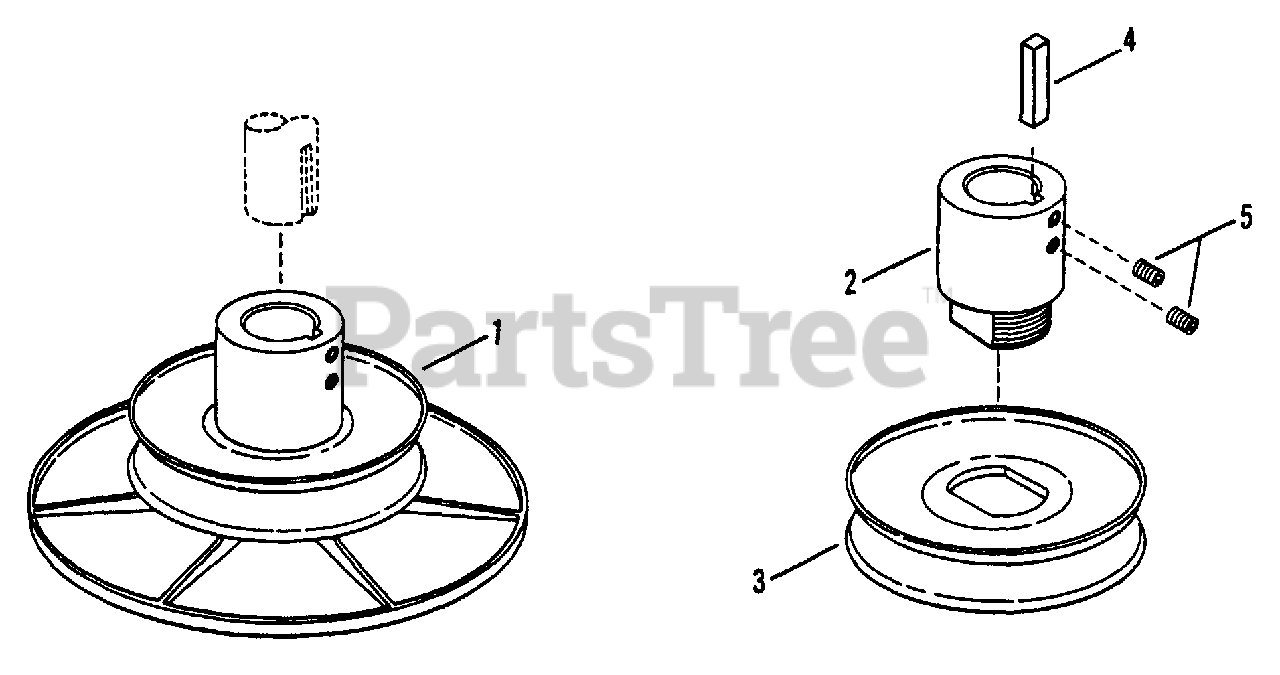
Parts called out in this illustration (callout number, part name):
1	ASSEMBLY, Drive Disc
2	HUB
3	PULLEY, Drive
4	KEY
5	SCREW, 3/8-16 x 3/8" Set
